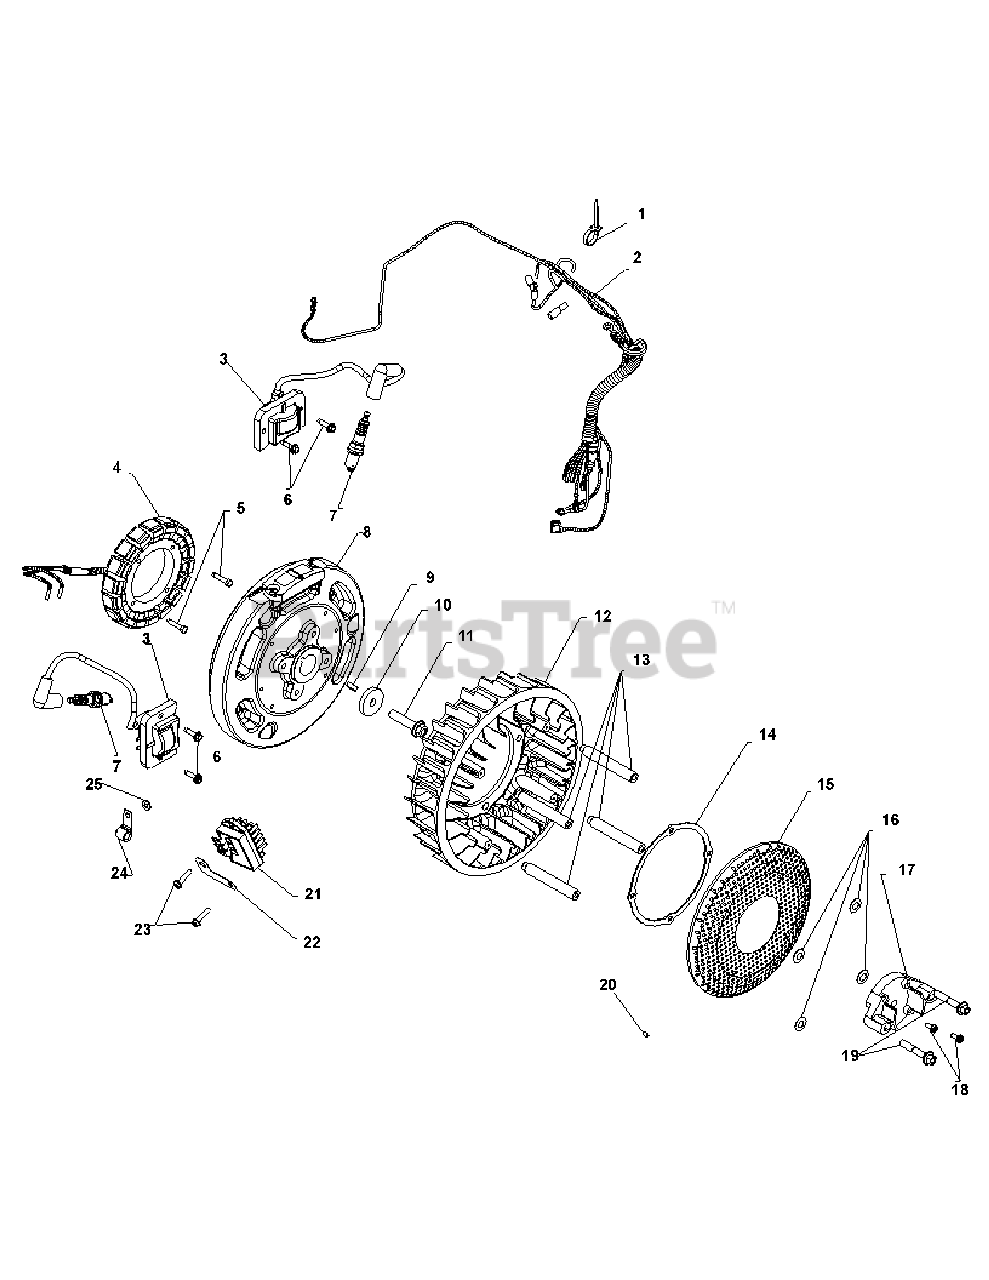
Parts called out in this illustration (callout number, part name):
2	Harness, Wiring Assembly
3	Kit, Module Igntn (Cdi Fixed)
4	Kit, 15 / 20 Amp Stator
5	Screw, Thd Frm M5X0.8X25
6	Screw, Flg Thd Frm M5X.8X20
7	Plug, Spark (Std)
9	Key, 3/16'' X 5/8''
10	Washer, Flat 13/32''
11	Screw, Flg M10X1.5X45
12	Fan
14	Ring, Support
15	Screen, Grass
16	Washer, Spring 10 Mm
17	Adapter, Drive Shaft
18	Screw, Wsh Hd Tap #8-18X1/2''
19	Screw, Flg M8X1.25X45
20	Screw, Skt Set #10-24X1/4''
21	Regulator/Rectifier
22	Bracket, Ground Strap
23	Screw, Hex Flange Hi-Lo
24	Clip, Cable
25	Washer, Flat 1/4'' (O.D. 1/2'')
